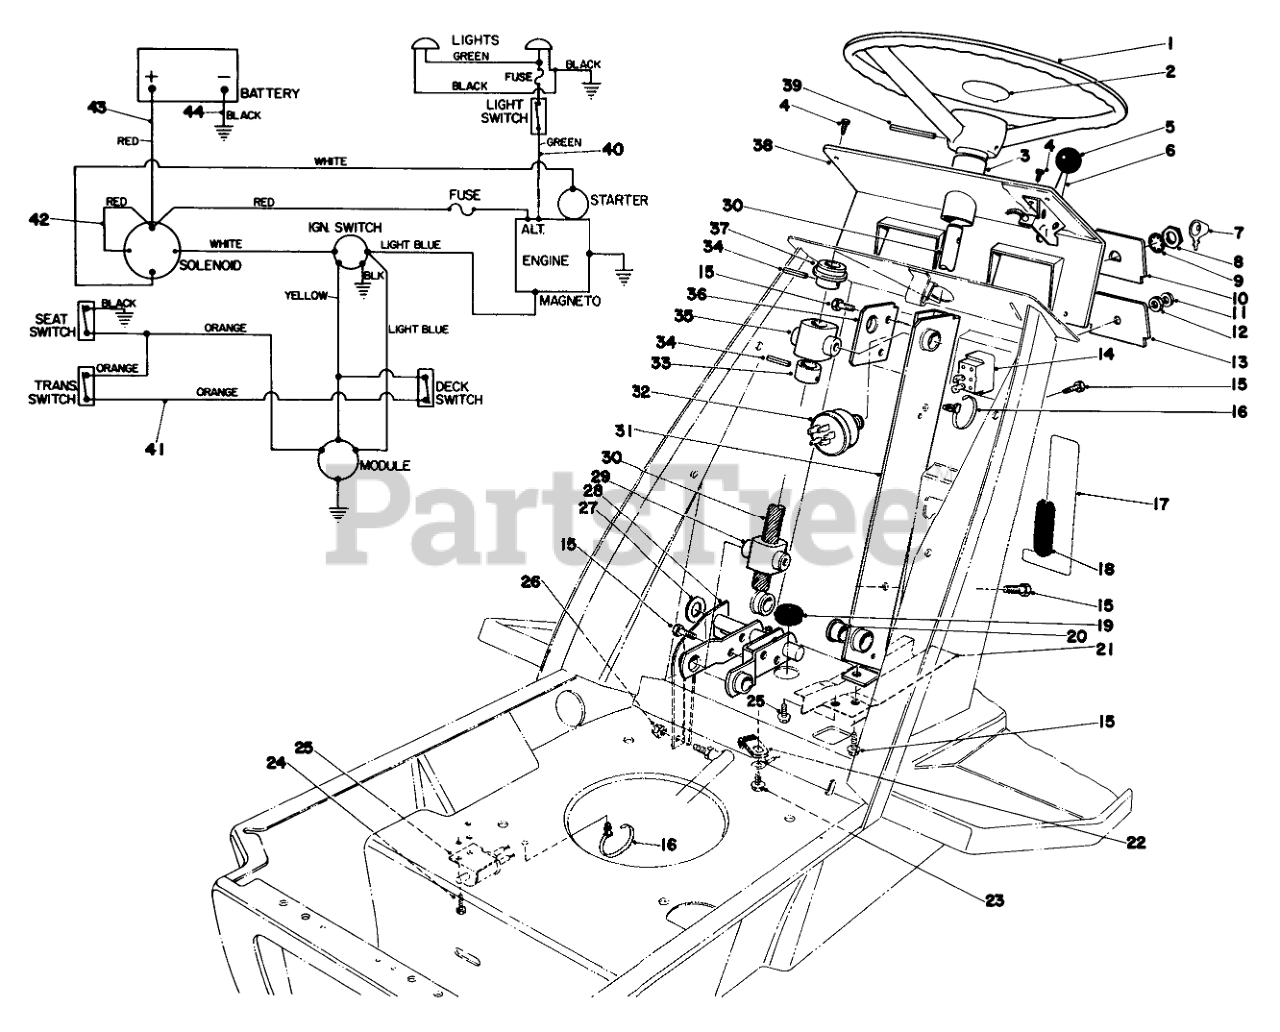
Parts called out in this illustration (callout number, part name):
1	Steering Wheel
2	Cap Steering Wheel
3	Tube Steering
4	Screw
5	KNOB-CONTROL
6	Throttle Control
7	Key
8	NUT-HH
9	WASHER-TOOTH, INTERNAL
10	DASH PANEL INSERT
11	NUT-BULB
12	NUT-LOCK
13	DASH PANEL INSERT
14	Light Switch (Incl. Ref. #11-12)
15	SCREW-HWHTF
16	TIE-MOUNT, PUSH
17	Decal-Deck
18	EDGE MOULDING
19	GROMMET
20	BEARING-FLANGE
21	WIRE HARNESS SHLD B
22	CLIP-FUEL LINE
23	SCREW-HWH
24	SCREW-TAPTITE
25	DECK INTERLOCK SWITCH
26	Nut
27	WASHER
28	STEERING LINK WA BO
29	FOLLOWER STEER SHAFT
30	STRG SHAFT
31	STRG BRKT B
32	Ignition Switch (Incl. Ref. #7-9)
33	STRG SHAFT COLLAR
34	PIN-SPRING
35	BRG STEERING SHAFT
36	STRG BRG SUPPORT
37	Collar Steering Shaft
38	DASH PANEL
39	PIN-ROLL
40	Wire Harness Light
41	WIRE HARNESS
42	SOLENOID WIRE
43	WIRE ASM
44	WIRE ASM
